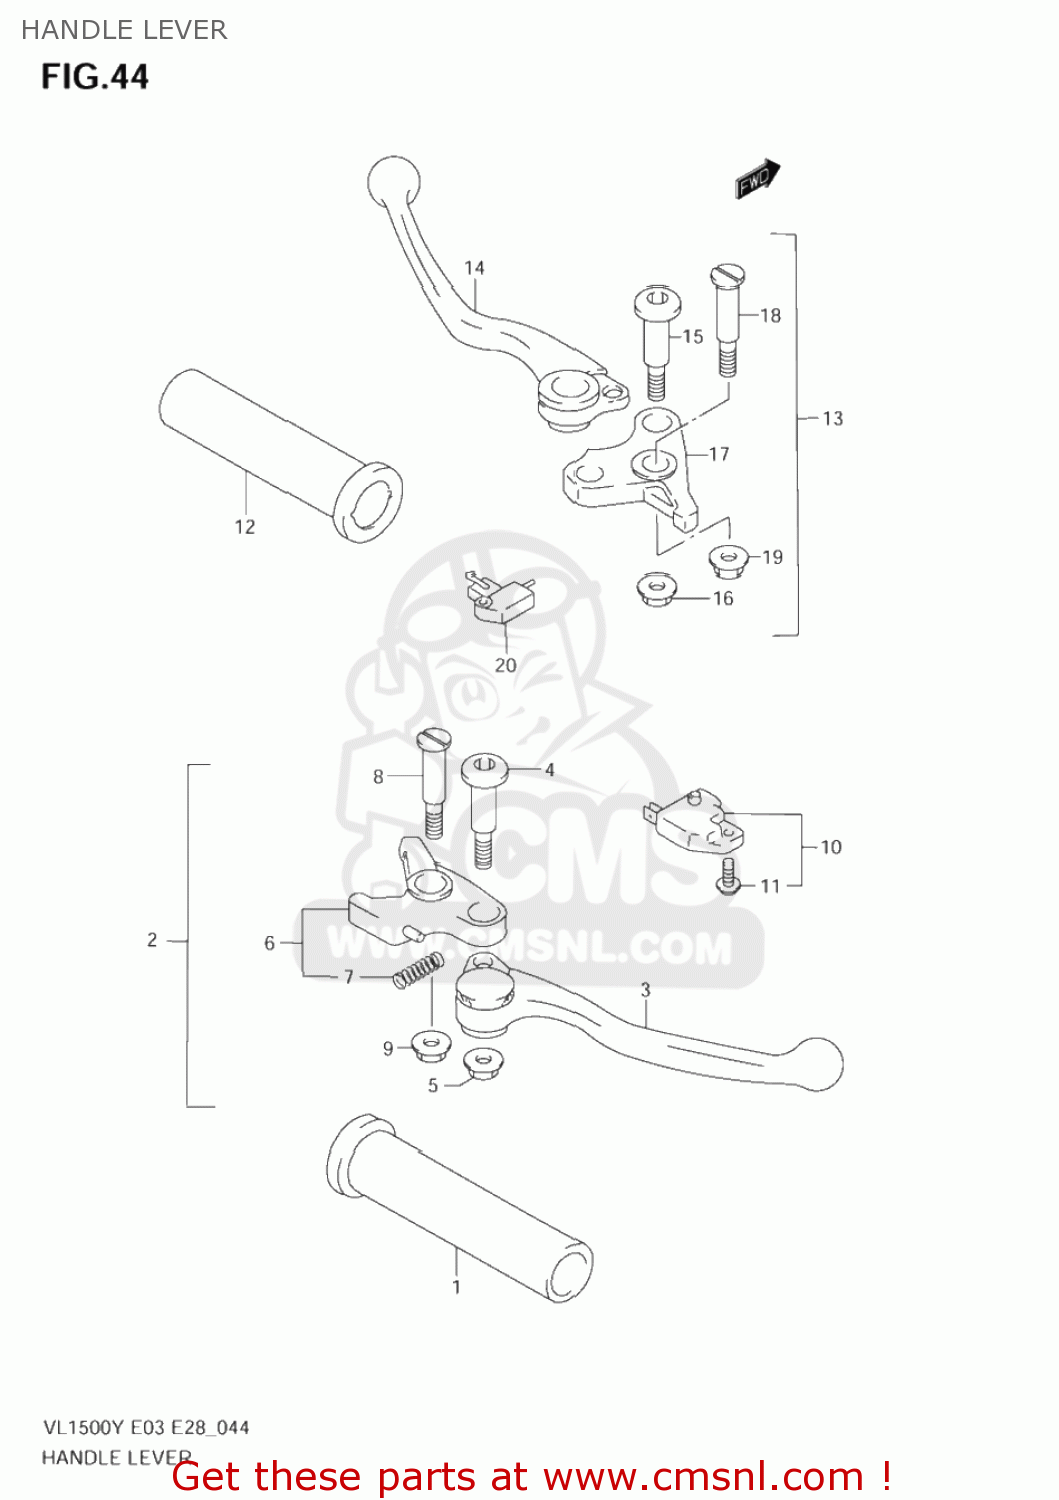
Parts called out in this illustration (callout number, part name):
1	GRIP,THROTTLE
2	LEVER ASSY,BRAKE
3	LEVER,ADJUST
4	BOLT,LEVER
5	NUT
6	RNOCKER
7	SPRING
8	BOLT,LEVER PIVOT
9	NUT
10	SWITCH ASSY,ST
11	SCREW
12	GRIP,L
13	LEVER ASSY,CLUTCH
14	LEVER ASSY,CLUTCH
15	BOLT,LEVER
16	NUT
17	KNOCKER
18	BOLT,LEVER PIVOT
19	NUT
20	SWITCH ASSY,CLUTCH
